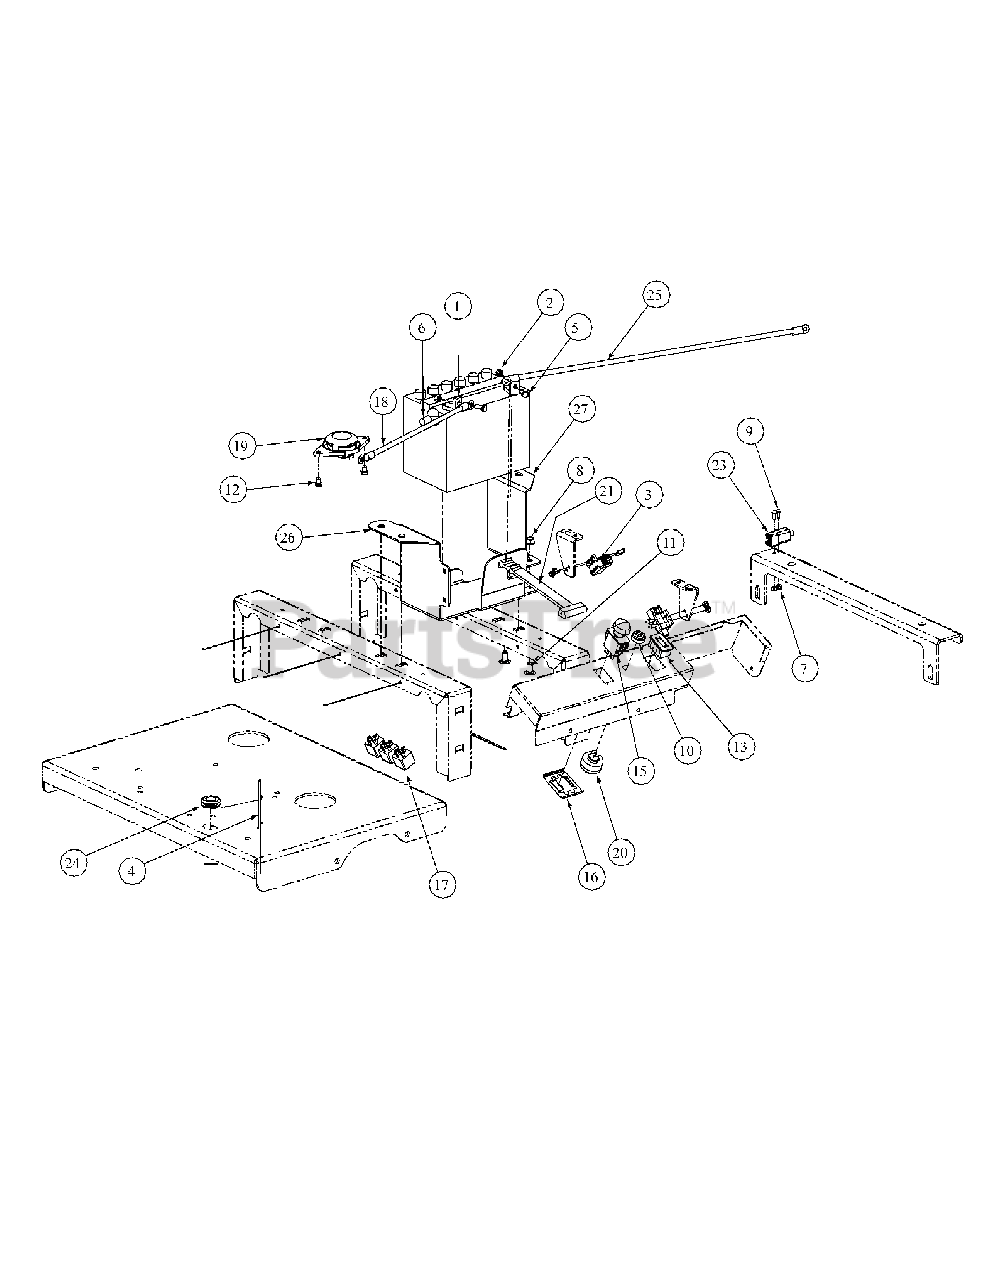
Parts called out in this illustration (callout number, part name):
1	Battery, 12V 225CCA 30 Min
2	Lock Nut, Nylon Insert, 1/4-20
3	Delta Switch
4	Cable Tie, 3/16 x .05 x 7.4
5	HHCS, 1/4-20, .75
6	Boot, OD Rubber Battery-PST Red
7	Lock Nut, Nylon Insert, 10-32
8	Hex Nut, 3/8-16 Flange Lock
9	Phillips Head Screw, Machine, 10-32 x 5/8
10	Nut, W/Cap, 5/8-32 Ignition
11	Carriage Bolt, 3/8-16 x .75 Long
12	Screw, TT, 1/4-20, 0.500, Hex Index Washer
13	Hour Meter
14	Harness, Hourmeter
15	Electric PTO Switch
16	Bracket, PTO Retainer Switch
17	Relay, 12V 40A
18	Battery Cable Red, 24"
19	Seat Switch
20	Ignition Switch, Pin
21	Battery Strap, 400
21	Harness Assembly
23	Plunger Switch
24	Grommet, .75 ID
25	Cable Battery Red, 24"
26	Bracket Mount, Battery
27	Bracket Mount, Battery
